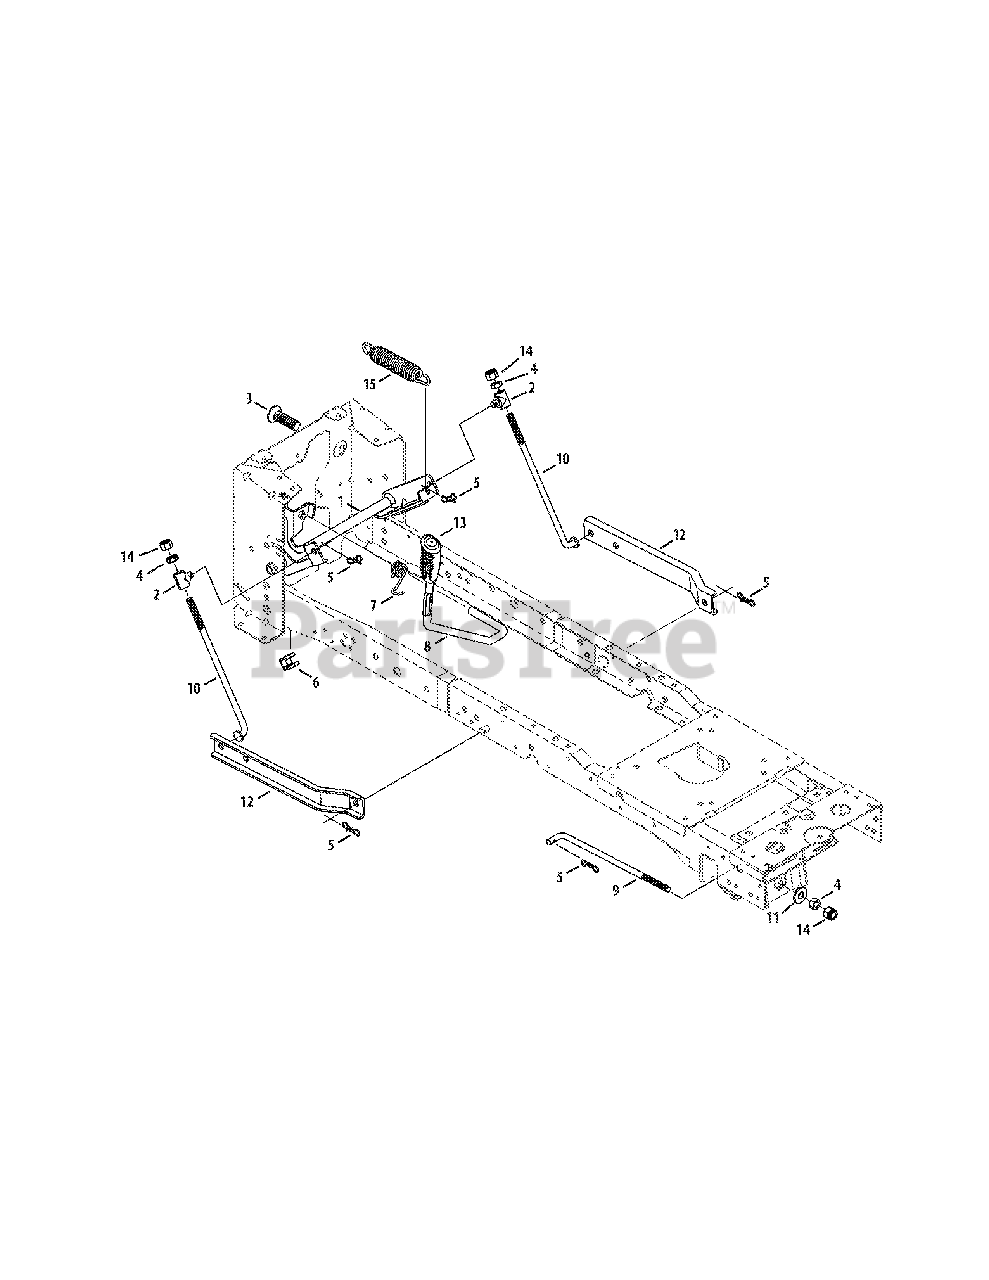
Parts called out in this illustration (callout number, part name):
1	Shaft Assembly, Lift
2	Ferrule, .510 x .496
3	Spring Insert
4	Nut, Jam, 1/2-13
5	Bow-Tie Cotter Pin
6	Spacer, .76 ID x .93 LG
7	Torsion Spring
8	Deck Lift Handle
9	Deck Lift Rod
10	Lift Adjustment Link
11	Pivot Cup
14	Hex Lock Nut, 1/2-13
15	Lift Assist Spring
